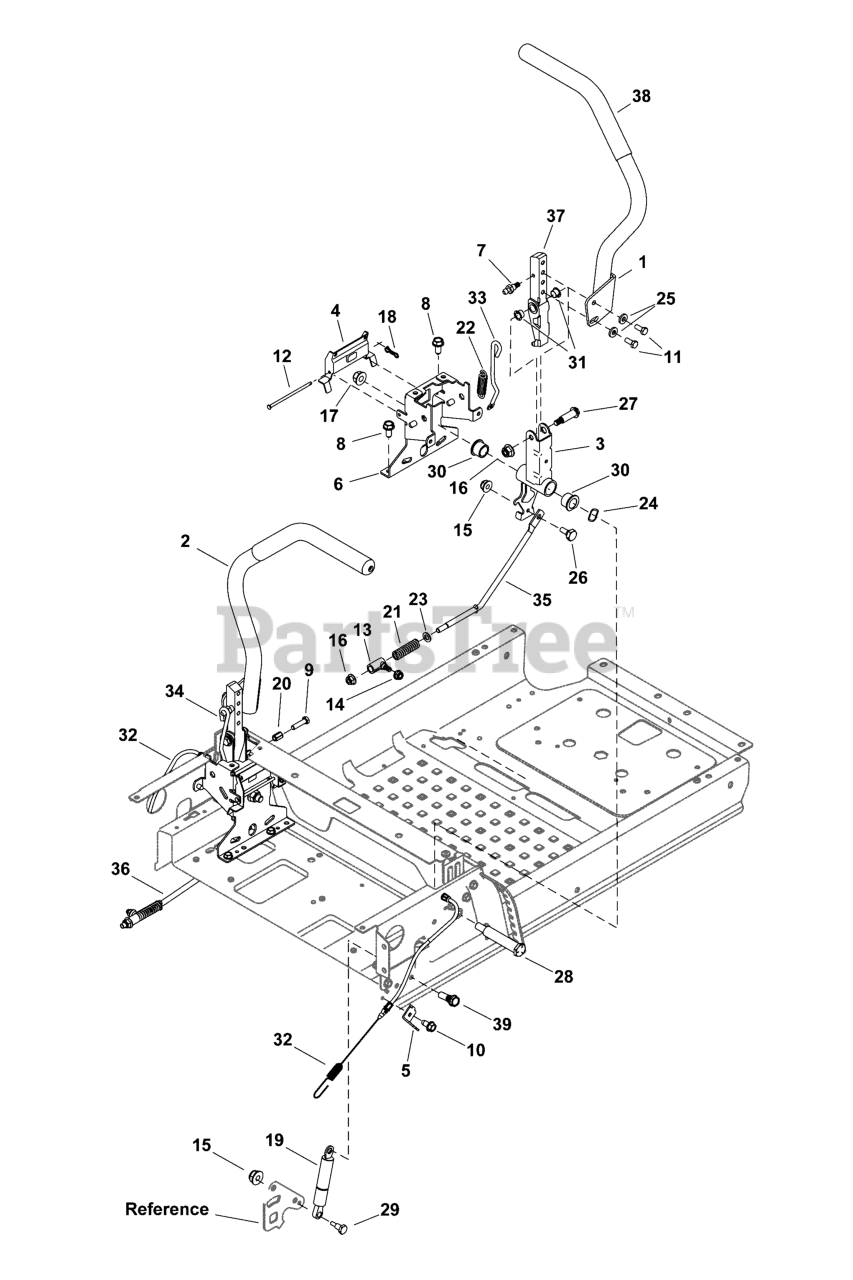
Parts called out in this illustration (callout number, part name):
1	ASSEMBLY, RH Lapbar Lever
2	ASSEMBLY, LH Lapbar Lever
3	BRACKET, Lapbar Pivot
4	ACTUATOR, Brake Lever
5	BRACKET, Brake Cable
6	BRACKET, Lapbar Pivot Support
7	SCREW, 5/16-18 X .48, Shoulder Ball
8	SCREW, 5/16-18 X .750, Hex Washer
9	SCREW, 5/16-18 X 1.25, Hex Cap
10	SCREW, TT, 1/4-20 x 1/2
11	SCREW, 5/16-18 X .75, Hex Head Patch
12	PIN, .188 X 4.1
13	FERRULE, 3/8 ID X .420, Shoulder
15	NUT, Flange Nylock , 1/4-20
16	NUT, 3/8-16, Flanged Lock, GR5
17	NUT, 1/2-13, Flange Lock
18	PIN, 1/4-5/16, Bow Tie Cotter
19	DAMPENER, .87 OD X 7.06 LG
20	NUT, 5/16-18
21	SPRING, .45 X 3.215, Compression
22	SPRING, .56 X 2.31 X .105, Extension
23	WASHER, .385 X .62 X .063, Flat
24	WASHER, .785 X 1.0 X .012, Wave
25	WASHER, .344 X .750 X .120, Flat
26	SCREW, .375 DIA. X .181, Shoulder
27	SCREW, .498 DIA. X 1.296, Shoulder
28	SCREW, .75 X 3.25 X 1/2-13, Shoulder
29	SCREW, .395 DIA. X .56, Shoulder
30	BEARING, .75 X 1.00 X .73
31	BEARING, .500 X .627, Flange
32	CABLE, Park Prake
33	ROD, Lapbar Detent, RH
34	ROD, Lapbar Detent, LH
35	ROD, Hydro Control, RH
36	ROD, Hydro Control, LH
37	ARM, Lower
38	GRIP, Lapbar
39	SCREW, .395 DIA. X .83, Shoulder
